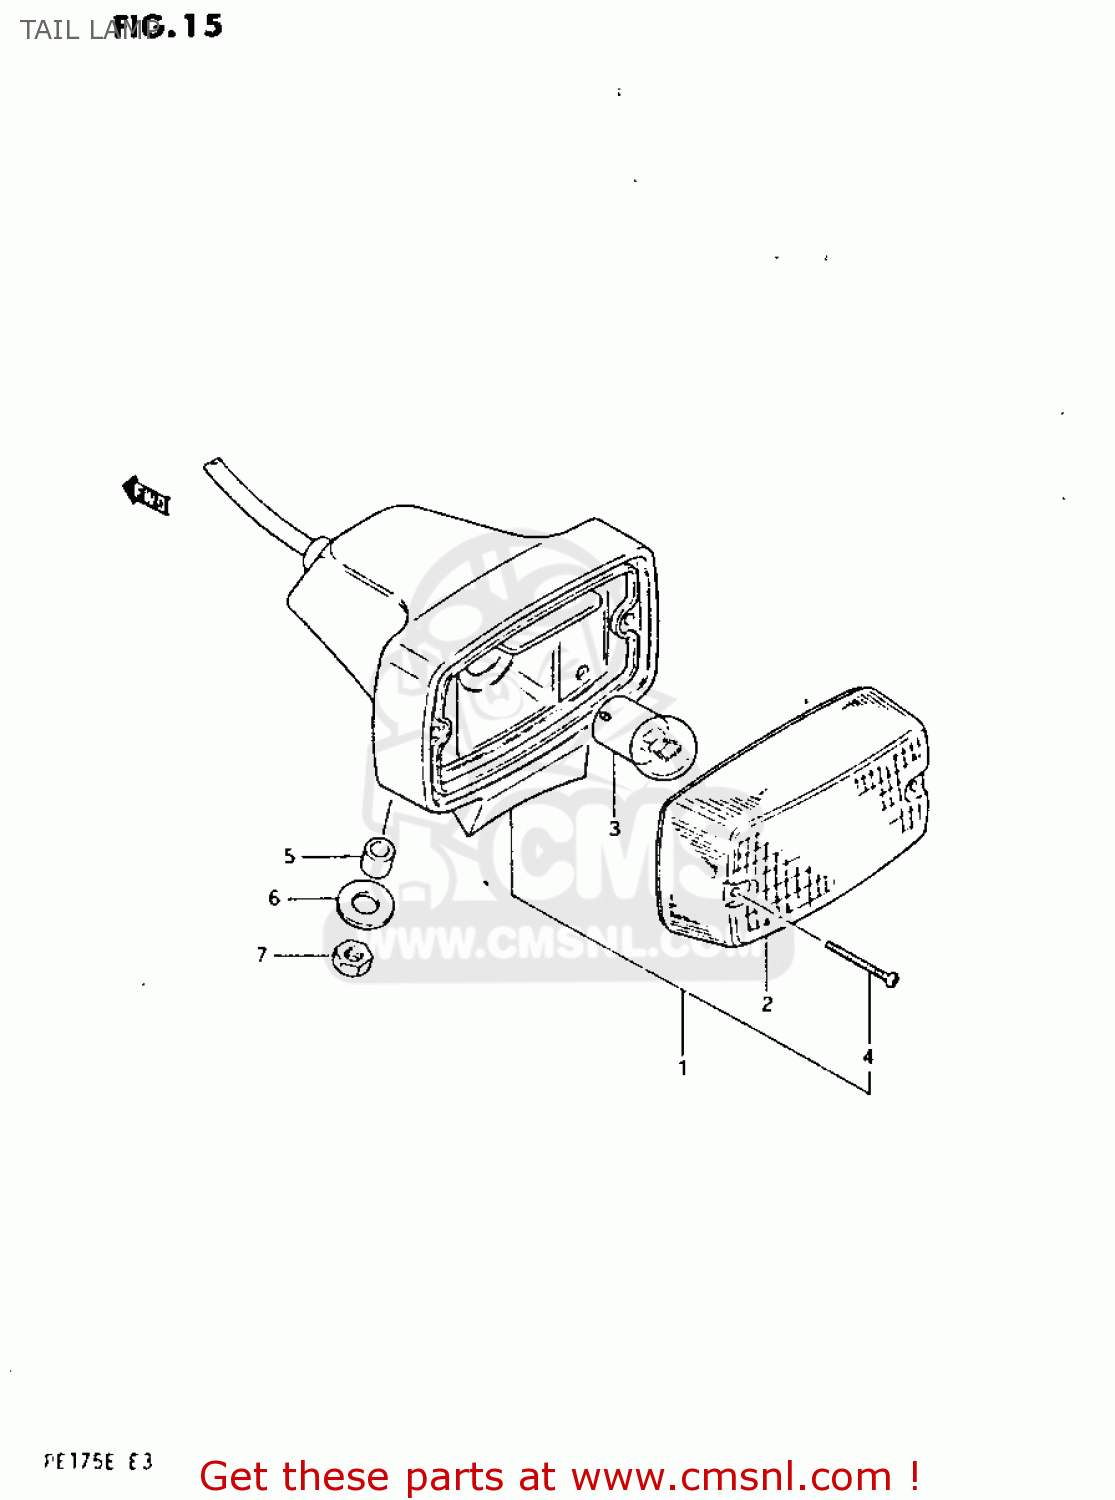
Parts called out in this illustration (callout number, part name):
1	LAMP ASSEMBLY,TAIL
2	LENS
3	BULB(6V5W,TOKAI DENSO)
4	SCREW,REAR COMBINATION LAMP LENS
5	SPACER (6.1X9X9)
6	WASHER
7	NUT
